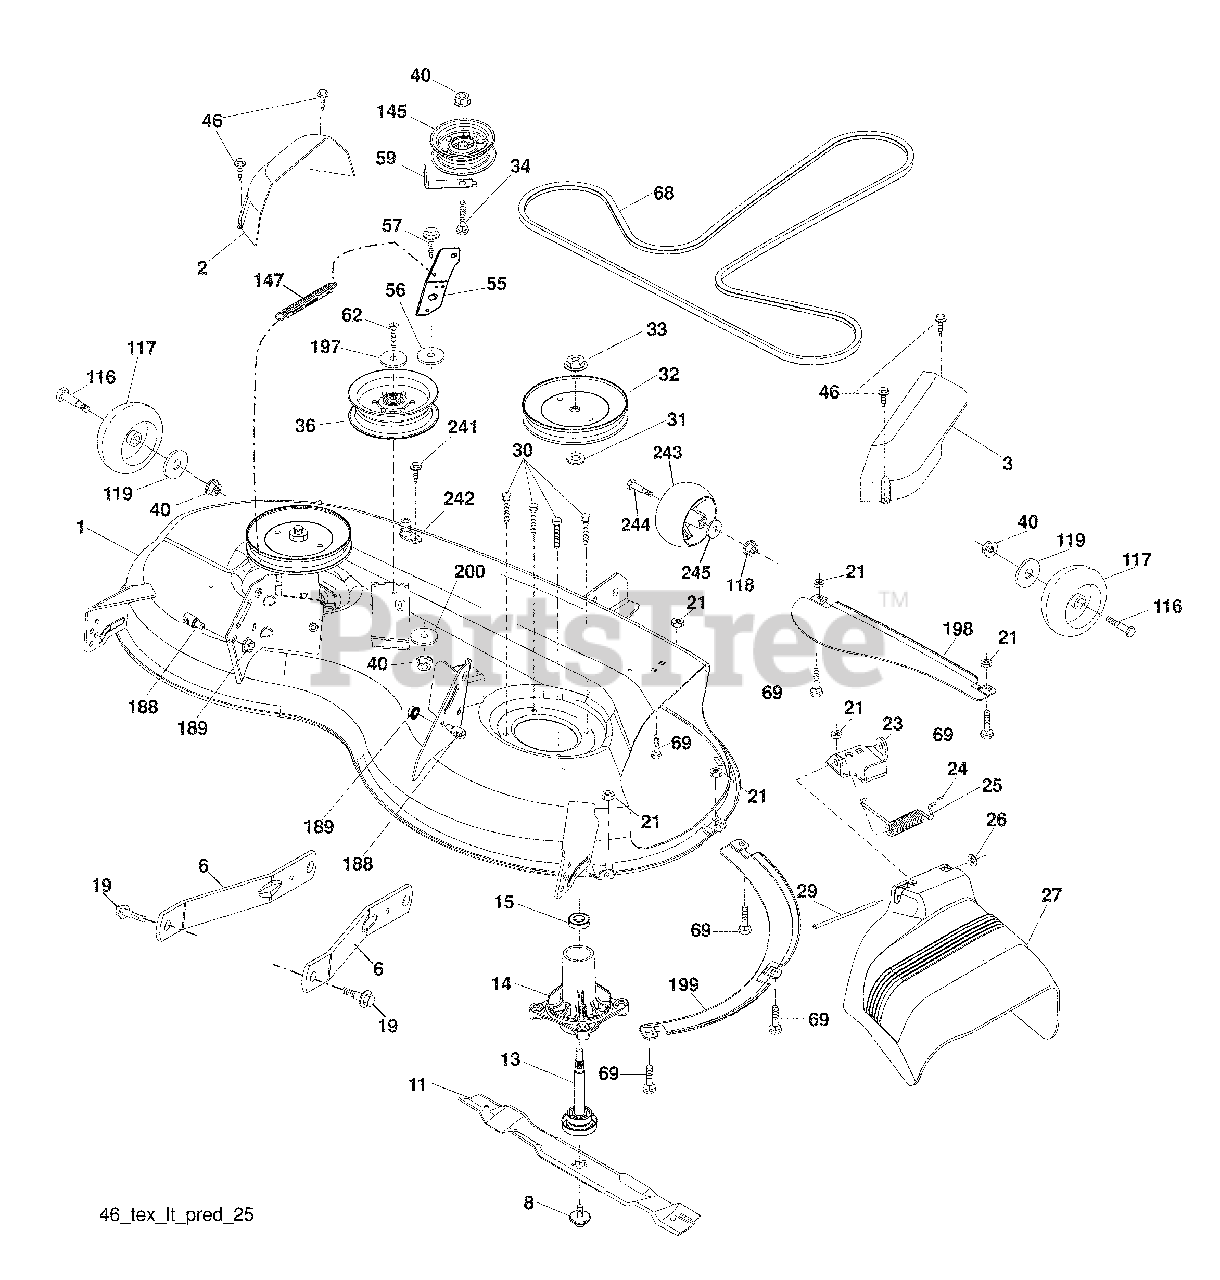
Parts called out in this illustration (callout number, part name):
1	Mower Housing
2	Cover Mandrel RH
3	Cover Mandrel LH
6	Arm Suspension
8	Bolt/Washer asm 7/16-20 unf
11	Blade Mower Hi Lift
13	Shaft Assembly, Mandrel
14	Housing, Mandrel
15	Bearing, Ball, Mandrel
19	Bolt, Shoulder
21	Nut
23	Bracket, Deflector
24	Cap, Sleeve
25	Spring, Torsion, Deflector
27	Shield, Deflector
29	Rod, Hinge
30	Screw Thdrol Rolling Wsh Hd
31	Washer, Spacer
32	Pulley, Mandrel
33	Nut, Toplock, Flanged
34	Bolt Carr Sh. 3/8-16 x 1-1/2 Gr. 5
36	Pulley, Idler, Flat
40	Nut, Lock Flg. 3/8-16 unc
55	Arm, Idler
56	Spacer, Retainer
57	Screw Hexwsh Thd 3/8-16 x 1
59	Guard, Tuv Idler (94)
62	Bolt 3/8-16 unc x 2-1/4 Gr. 5
68	V-Belt
69	Bolt
116	Bolt, Shoulder
117	Wheel, Gauge
118	Nut Centerlock 3/8-16 unc
119	Washer 13/32 x 1-1/2 x 11 Ga.
145	Pulley Idler
147	Spring Return
188	Stud Fastener
189	Nut Lock Hex Flange
197	Washer 13/32 x 13/16 x 12 Ga.
198	Baffle Center Front
199	Baffle Front RH
200	Washer 13/32 x 1 x 1/2 11 GAHRD
242	Washout Port
243	Wheel Gauge Half Spoked
244	Bolt Shoulder "A" 2.41. "B" 1.66
245	Washer 3/8 x 7/8 x 14 Ga.
